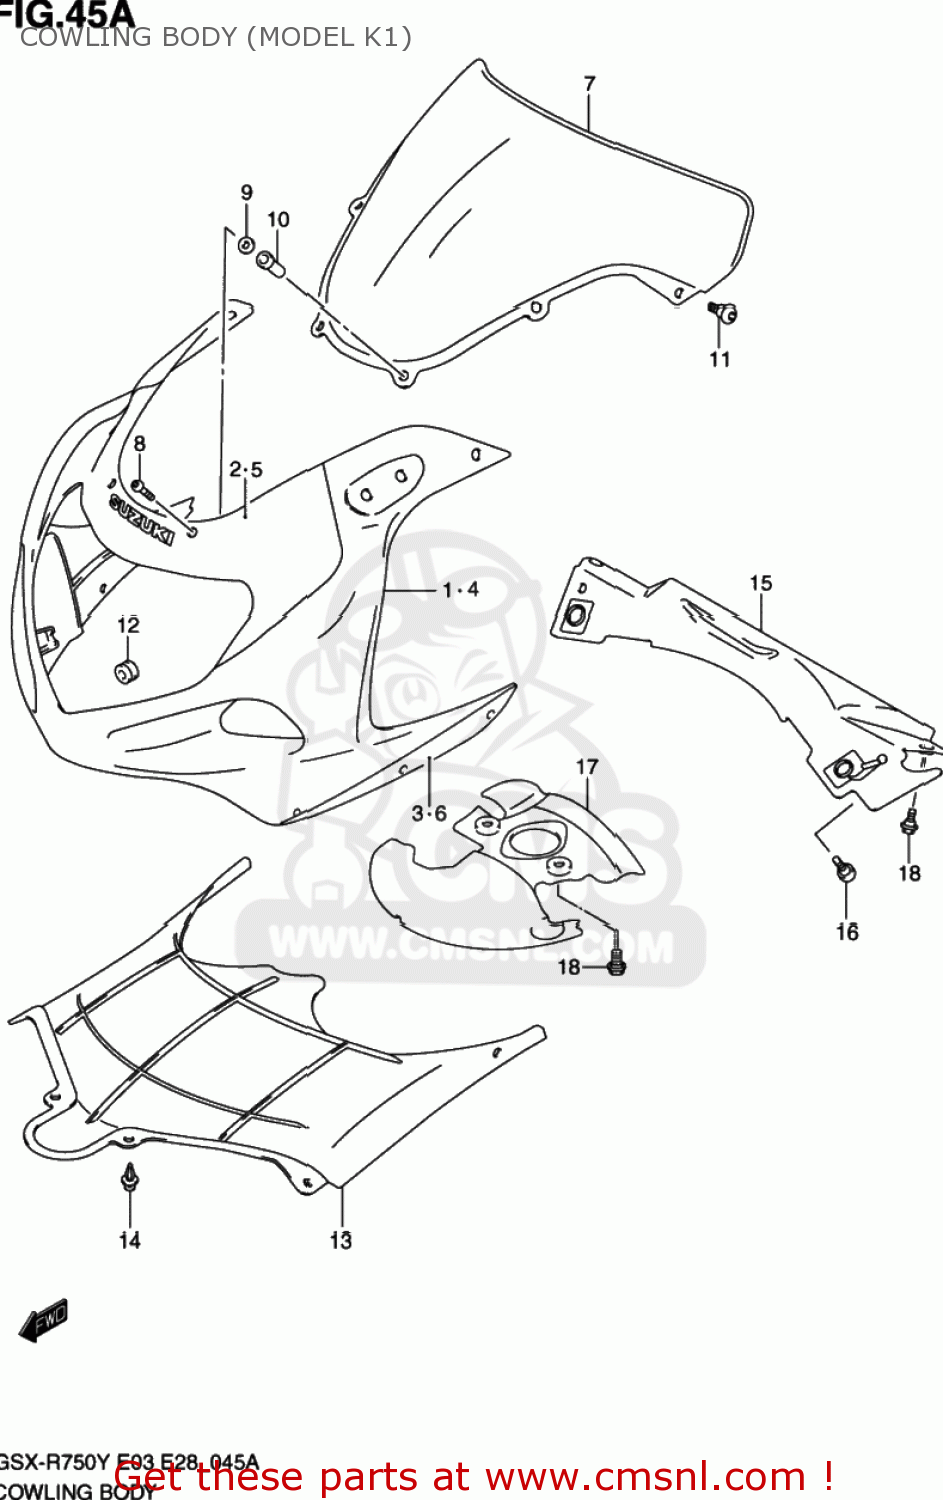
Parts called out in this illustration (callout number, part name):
1	COWLING,BODY(BLUE)
2	TAPE,COWL BODY FR
3	TAPE SET,COWL BODY SIDE
4	COWLING,BODY(BLACK)
5	TAPE,COWL BODY FR
6	TAPE SET,COWL BODY SIDE
7	WINDSCREEN
8	SCREW(5X14)
9	WASHER
10	NUT
11	SCREW(5X16)
12	CUSHION
13	COVER,BODY COWLING
14	CLIP(BLACK)
15	COVER,COWLING FR LWR
16	SCREW(5X16)
17	COVER,LWR BRACKET
18	BOLT
